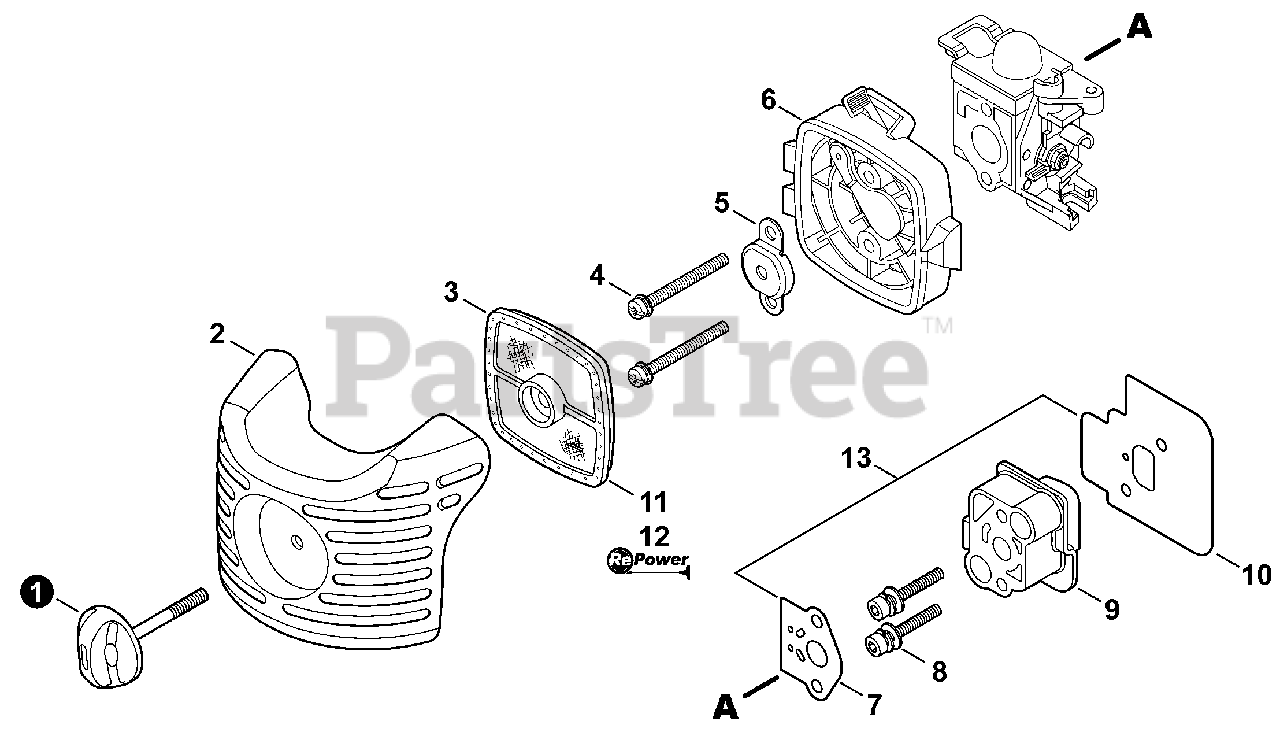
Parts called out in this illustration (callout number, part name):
1	THUMBSCREW
2	COVER, AIR FILTER
3	FILTER, AIR - DOUBLE LAYER
4	SCREW 5×65
5	PLATE, PREVENT
6	CASE ASSY, AIR FILTER
7	GASKET, INTAKE
8	BOLT 5×25
9	INSULATOR, INTAKE
10	HEAT SHIELD, INTAKE
11	TUNE-UP KIT - REPOWER
12	FILTER KIT - REPOWER
13	GASKET KIT
